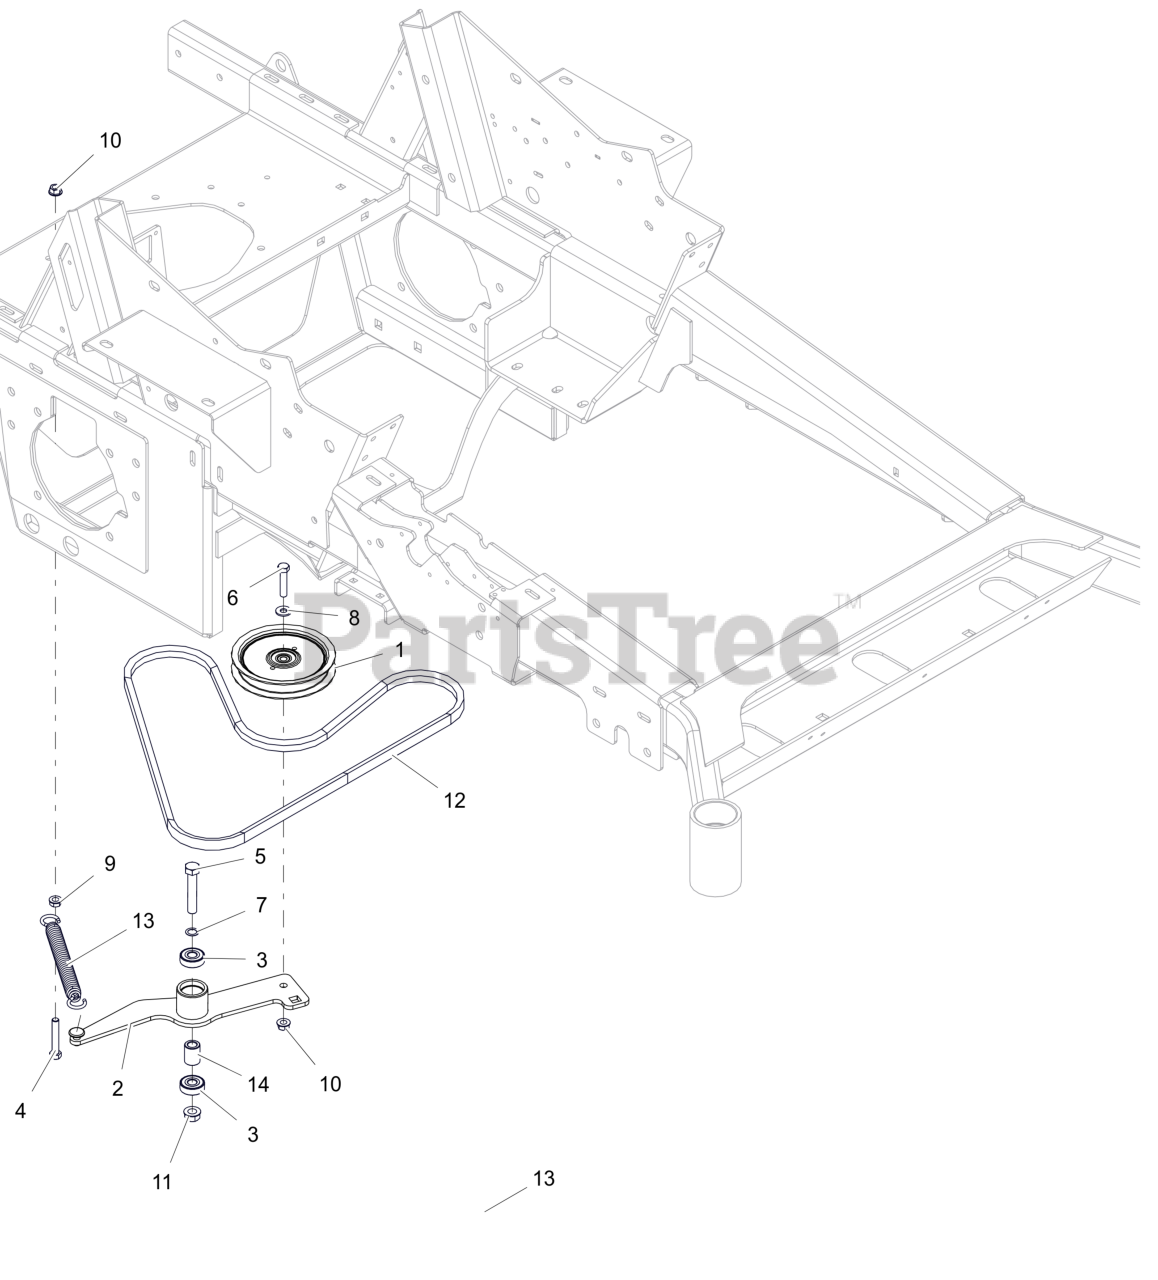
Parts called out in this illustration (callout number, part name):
1	IDLER, FLAT-5.00X.75
2	WLDMT, TRANSAXLE DRIVE IDLER ARM
3	BRG-BALL .500X1.38X.437
4	BLT,HEX .38-16X2.25 G5 ZCC
5	BLT,HEX .50-13X2.75 G5 ZCC
6	BLT, HEX .38-16X1.75 G5 ZCC
7	WASHER, .500X.750X.020 THRUST
8	WSHR,FLT .375X.875X.083 ZCC
9	NUT, SPNLK-FLG .38-16 G5 ZCC
10	NUT-LK-CTR-FLG .375-16 GF ZCC
11	NUT-LK-CTR-FLG .500-13 GG ZCC
12	V-BELT, HB RAW COGGED
13	SPRING- EXTENSION
14	SPACER .510 X .867 X 1.1485
